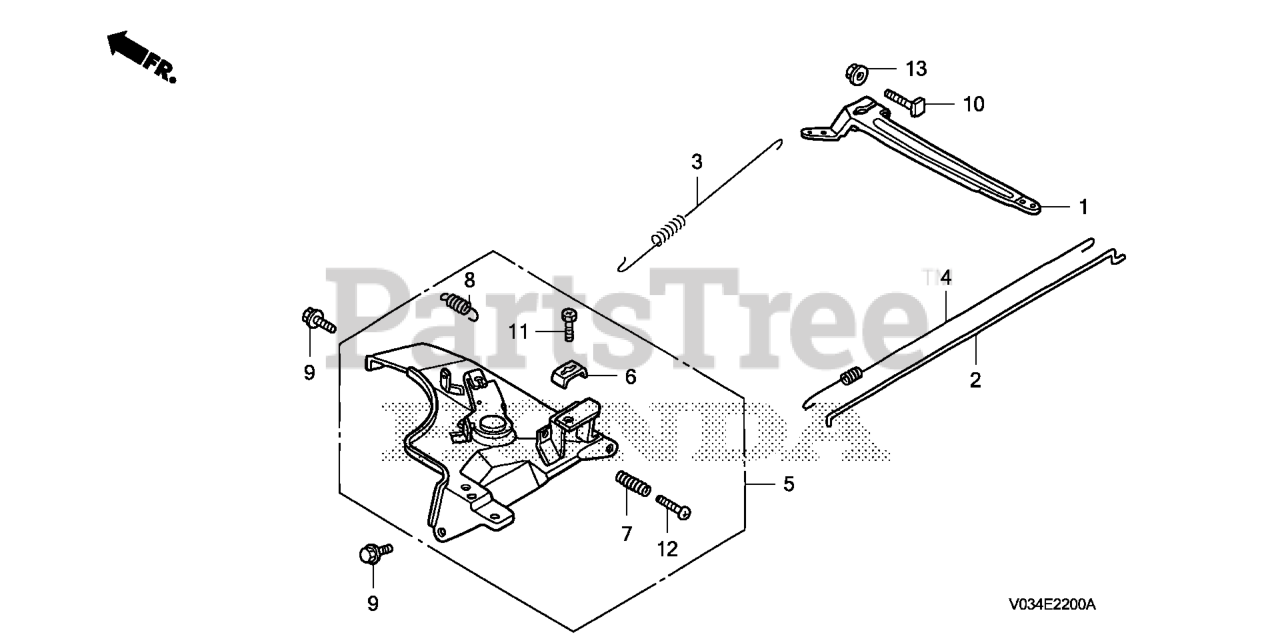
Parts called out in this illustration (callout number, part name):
1	ARM, GOVERNOR
2	ROD, GOVERNOR
3	SPRING, GOVERNOR
4	SPRING, THROTTLE RETURN
5	CONTROL ASSY.
6	HOLDER, CABLE
7	SPRING, CONTROL ADJUSTING Use from Engine SN 2327377.
8	SPRING, CONTROL LEVER RETURN
9	BOLT, FLANGE (6X12) (CT200)
10	BOLT, GOVERNOR ARM
11	BOLT, RECESSED (5X16)
12	SCREW, PAN (5X32)
13	NUT, FLANGE (6MM)
